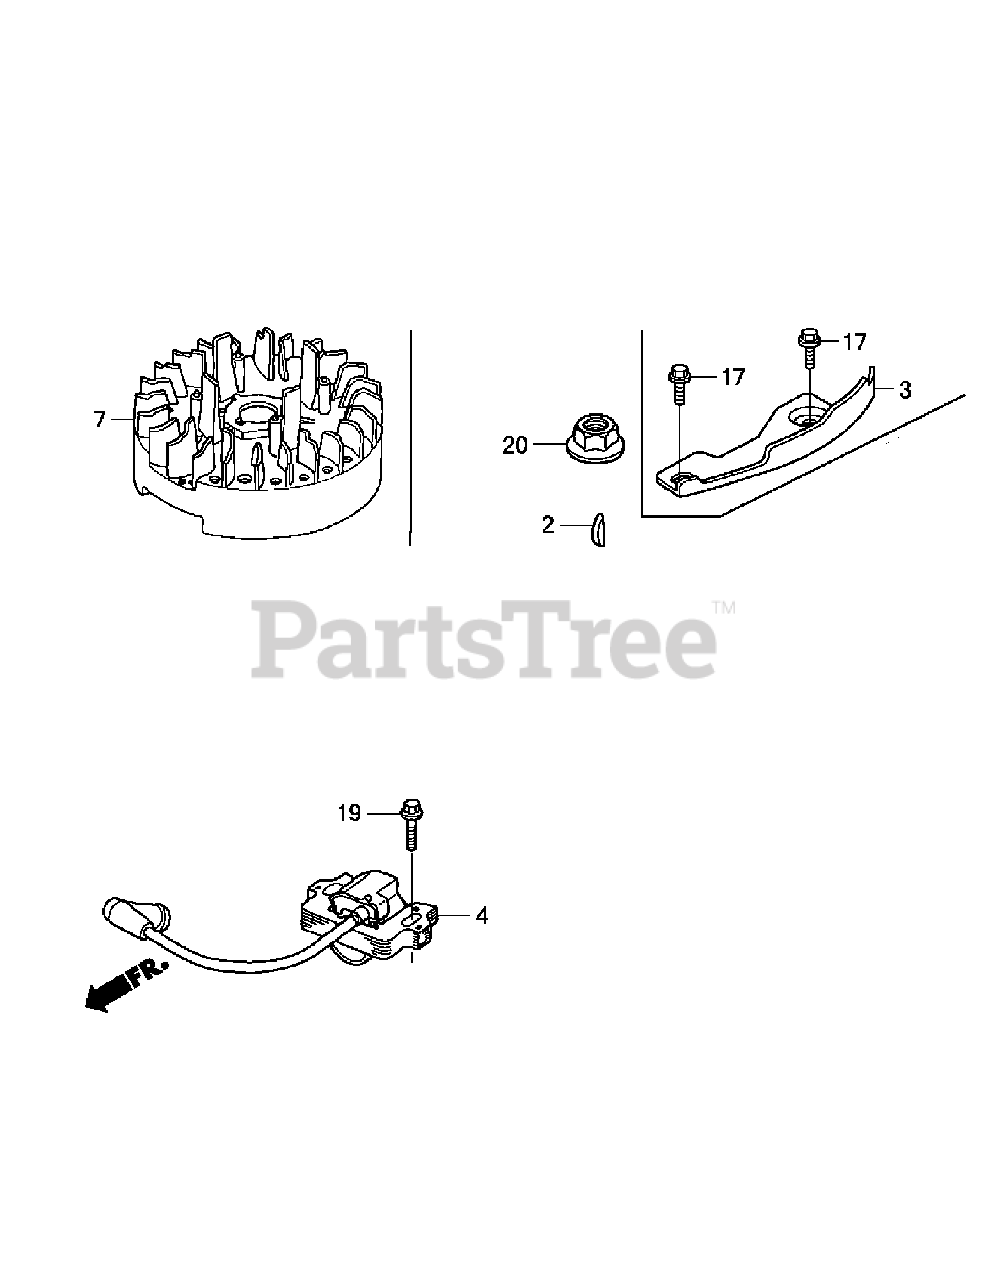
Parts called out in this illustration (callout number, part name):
2	Key, Special Woodru
3	Plate, Side
4	Coil Assy., Ignition (Phelon)
7	Flywheel Comp. (Phelon)
17	Bolt, Flange (6x12) (Ct200)
19	Bolt, Flange (6x20) (Ct200)
20	Pri; Nut, Special (14mm)
